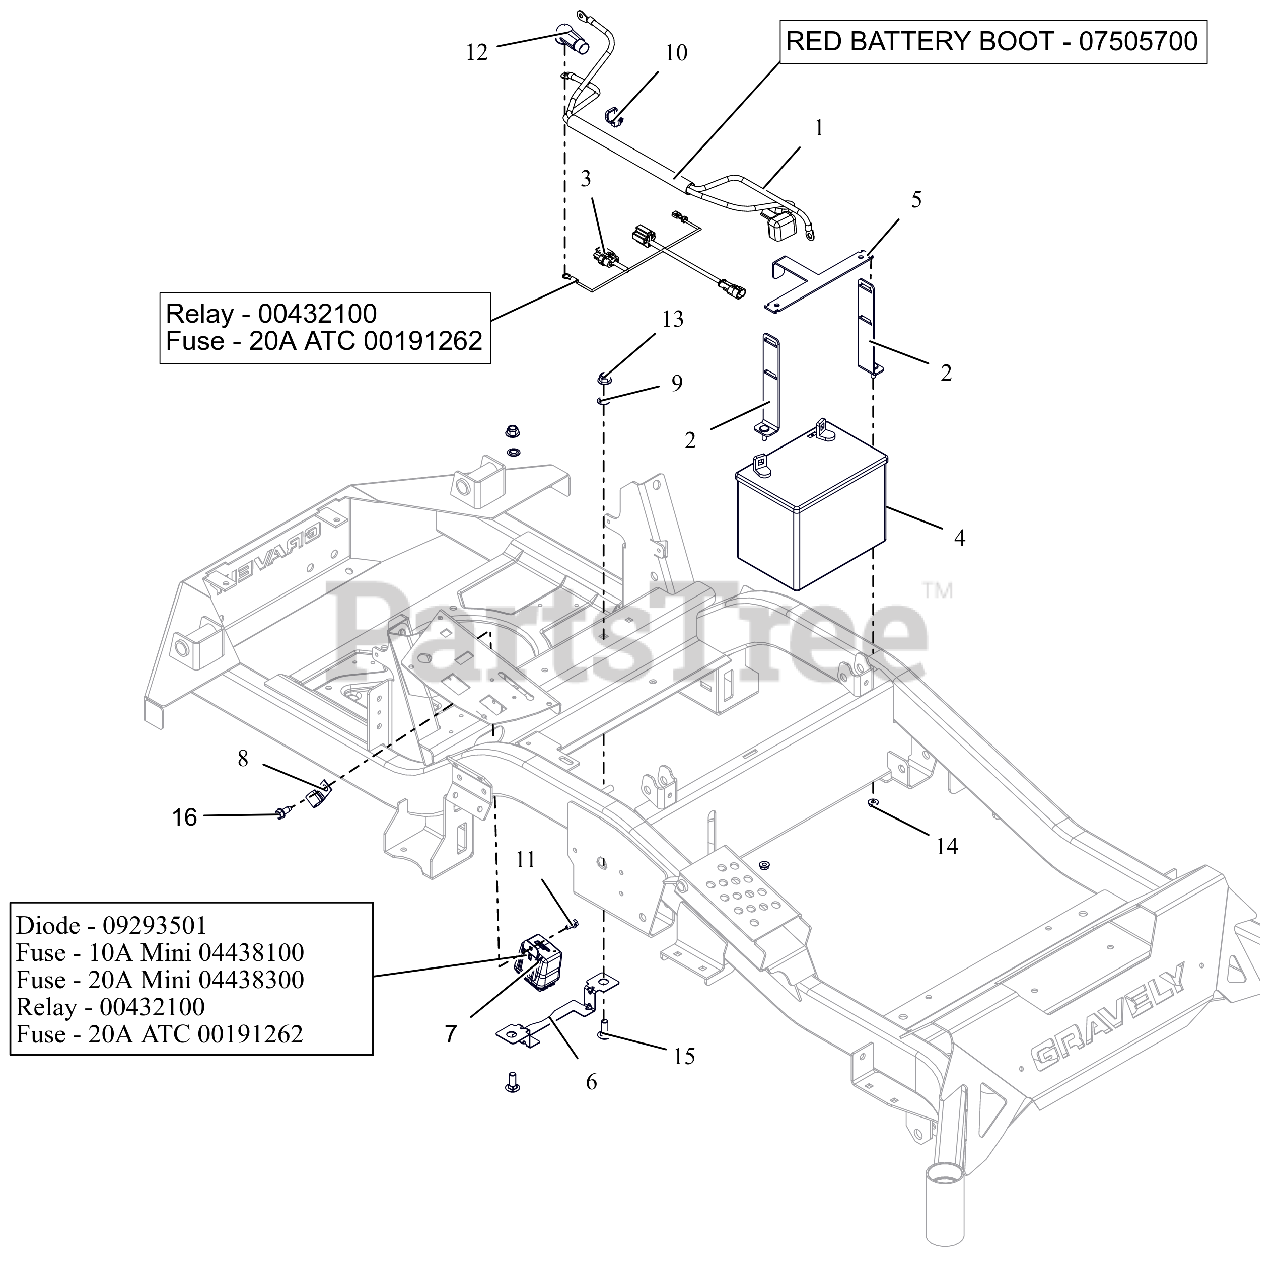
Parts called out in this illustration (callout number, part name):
1	HARNESS, BATTERY HD
1	INSULATOR
2	WMT,BATTERY MOUNT HOLD DOWN
3	HARNESS, STARTER ADAPTER
3	RELAY,SEALED W/DIODE
3	FUSE, 20 AMP BLADE S/O
4	BATTERY, 300 CCA 10U1L
5	BRKT, BATTERY TIE DOWN
6	GUARD, ELECTRICAL HARNESS
7	HARNESS, WIRE
7	DIODE, CONNECTOR SHELL
7	FUSE,10 AMP MINI-ATC
7	FUSE,20 AMP MINI ATC
7	RELAY,SEALED W/DIODE
7	FUSE, 20 AMP BLADE S/O
9	NUT-PUSH .38 DIA. PAL ZINC
10	CABLE TIE W/ TREE (.25 HOLE)
11	SCR-TAP .25-20X.50 HWH ZCC
12	BOOT, .65ID POS
13	NUT,NYL-FLG .38-16 GF ZCC
14	NUT-LK-TOP-FLG .250-20 GF ZCC
15	BLT, RHSN .38-16X1.00 G5 ZCC
16	SCR,TAP .312-18X.75 HWH TR ZCC
